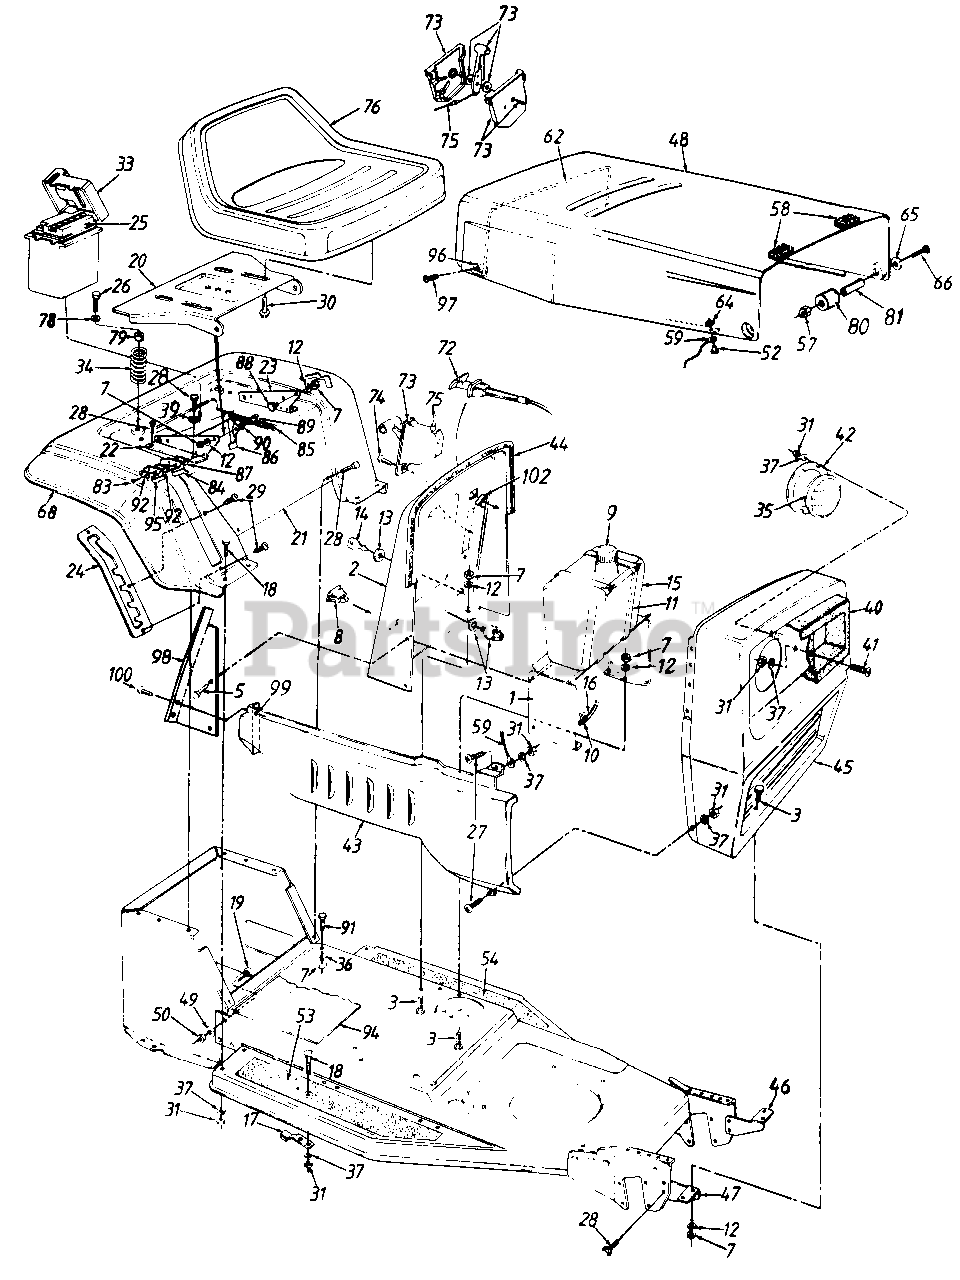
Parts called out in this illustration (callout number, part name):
1	Dash Panel Support Brkt.
5	Hex AB-Tap Scr. 1/4 x .62"
7	Hex Nut 5/16-18 Thd.
8	Light Switch
9	Gas Cap
11	Cable Tie
12	L-Wash. 5/16" I.D.
13	Ignition Switch
14	Ignition Key
15	Fuel Tank
16	Gas Line - 15" Lg.
17	Blade Brake Ass'y.
18	Carriage Bolt 1/4-20 x .62"
19	Ribbed Neck Bolt 3/8-24 x .8"
20	Seat Pivot Brkt.
25	Battery
26	Hex Self-Tap Screw 5/6-18 x 1.25" Lg.
27	Truss Mach. Scr. 1/4-20 x .5" Lg.
28	Hex AB-Tap Scr. 5/16 x .75" Lg.
29	Torx Mach. AB-Tap Scr. 1/4 x .62" Lg.
30	Hex Self-Tap Scr. 3/8-16 x .75" Lg.
31	Hex Nut 1/4-20 Thd.
33	Battery Box w/Cover
34	Compression Spring
35	Headlight
36	Bell-Wash. 5/16" I.D.
37	L-Wash. 1/4" I.D.
39	External L-Wash.
41	C-Sunk Mach. Scr. 1/4-20 x 1.5"
42	Headlight Retainer
43	Side Panel - R.H.
44	Trim Strip 31" Lg.
47	Grille Mtg. Brkt. - R.H.
50	Hex L-Nut 3/8-24 Thd.
52	Truss Mach. Scr. #10-24 x .5" Lg.
53	Foot Pad - R.H.
54	Foot Pad - L.H.
57	Hex Lock Nut 1/4-20 Thd.
64	Hex Sems Nut #10-24 Thd.
65	Spr. Wash. .39" I.D. x .62" O.D.
66	Truss Mach. Scr. 1/4-20 x 1" Lg.
68	Trim Strip 81" Lg.
72	Choke Control
73	Throttle Control Box
74	Truss AB-Tap Scr. #10 x .5"
75	Throttle Wire
76	Seat Assembly
78	Flat Wash. .344" I.D. x .88" O.D.
80	Rubber Washer .38" I.D.
83	Hex Tap Scr. #8 x .5" Lg.
84	Safety Switch (Seat)
85	Ext. Spring 5.31" Lg.
86	Seat Lift Brkt.
87	Insulator Boss Plate
88	Shld. Bolt .437" Dia. x .162" Lg.
89	Shld. Bolt .437" Dia. x .268" Lg.
90	Spr. Wash. .445" I.D. x .75" O.D.
91	Hex Wash. Hd. Scr. 5/16-18 x .62" Lg.
92	Insulator Plate
94	Center Foot Pad
95	Safety Switch (Seat)
96	Hood Spring Retainer
97	Oval Hd. Self-Tap Scr. .5" Lg.
98	Side Panel Mtg. Brkt. - R.H.
99	Speed Nut #10-24 Thd.
100	Truss Mach. B-Tap Scr. #10 x .5" Lg.
102	Retainer Clip
